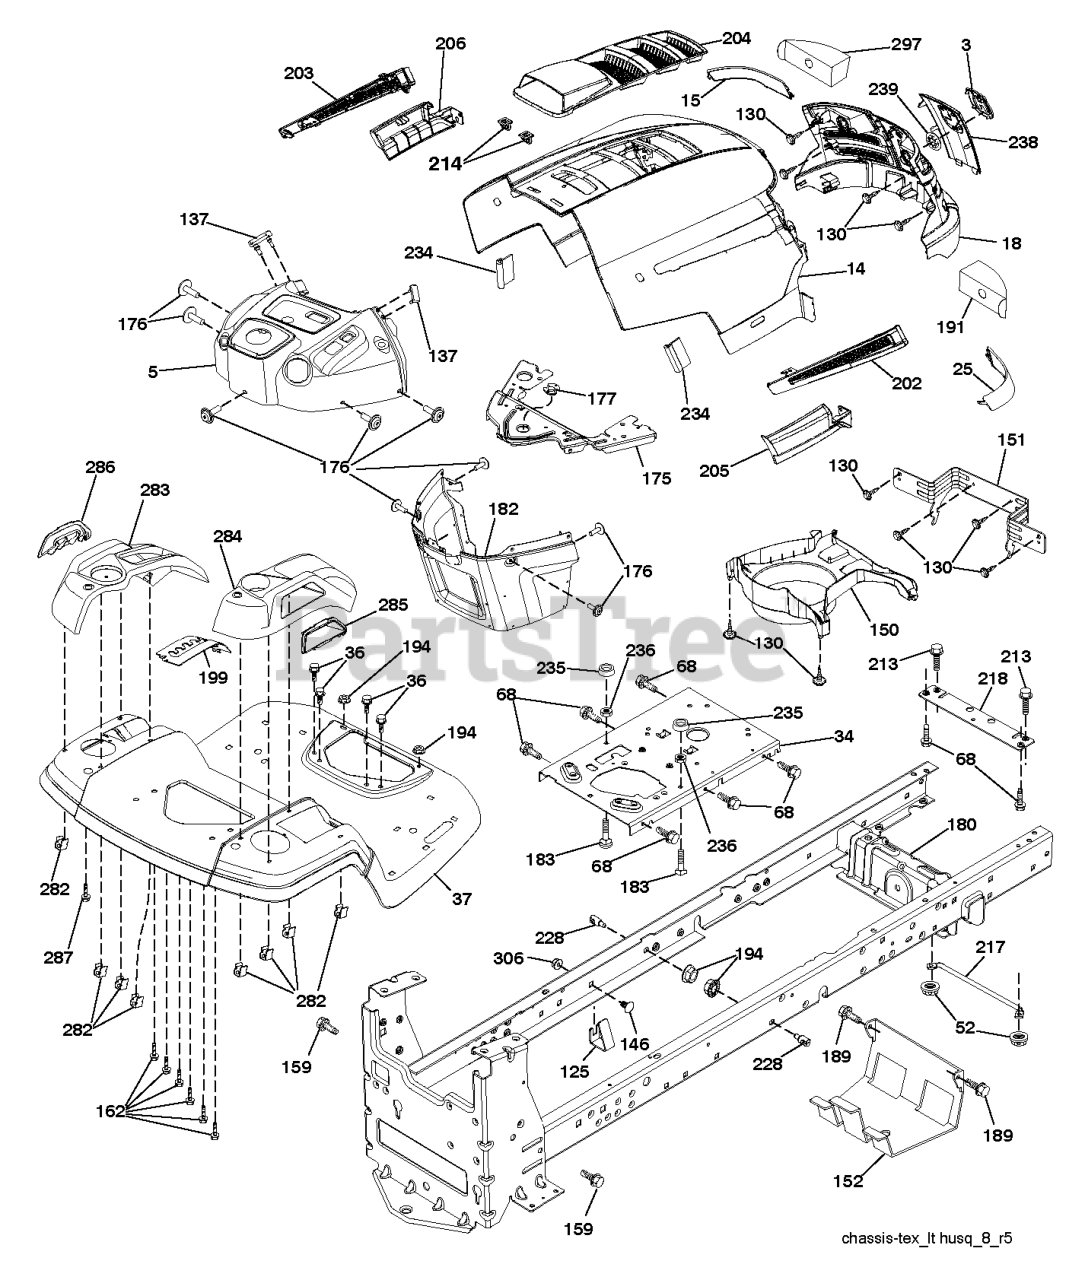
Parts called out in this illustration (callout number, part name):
3	RP LOGO
14	HOOD
15	LENS.HUSQVARNA LT.LH
18	GRILLE.SVC.HUSQVARNA.LT.GREY
25	LENS.HUSQVARNA LT.RH
34	PLATE.ENGINE.WELDED.CHASSIS
36	SCREW 5/16"
37	RP FENDER.TLT.FS.W/CPH.422
52	LOCKNUT
68	Screw 5/16-18 x 1/2 Hex, Self Tapping 5/16-18 x 1/2
125	CLIP.FUEL.LINE
130	SCREW.#10 X 0.750.BOS
137	BUMPER DASH
146	BOLT.RDHD.SHT.SQNK.3/8-16X5/8
151	BRACKET PIVOT
152	SHIELD.BROWNING.W/TEX
159	SCREW, 3/8-16X3/4
162	SCREW.HI-LO.CONSOLE
175	CROSSMEMBER
176	SCREW.#10-24X5/8.RN.QU
177	BUSHING STEERING
180	CHASSIS
182	DASH.LOWER.PREDATOR LT
183	BOLT.5/16-18X1-1/4 FULL.THREAD
189	SCREW
191	INSERT.REFLECTIVE.RH.
194	NUT LOCK HEX FLANGE 5/16-18
199	PLATE.DECK.LIFT.HUSQ.LT
202	VENT SIDE HOOD LH
203	VENT SIDE HOOD RH
204	VENT TOP HOOD
205	SKIRT SIDE RH
206	SKIRT SIDE LH
213	BOLT
214	CLIP.RETAINER.TINNER.
217	ROD.PIVOT.HOOD
218	X-PIECE.HOOD.STOP.NON/
228	STUD.FASTNER.W/ANTI-ROTATE
234	BUMPER.HOOD.TEX.HUSQVARNA
235	SPACER FENDER
236	NUT.CENTERLOCK.5/16-
238	TRIM
282	CLIP.RETAINER.CONSOLE.LT.HUSQ
283	CONSOLE.DECK.LIFT.HUSQ.N/FR.GR
284	CONSOLE.CNTRL.
285	CONSOLE INSERT RH
286	CONSOLE.INSRT.LH.HUSQ.LT.BLACK
287	SCREW 1/4X20
297	INSERT REFLECTIVE
306	NUT LOCK FLG 3/8-16 UNC
